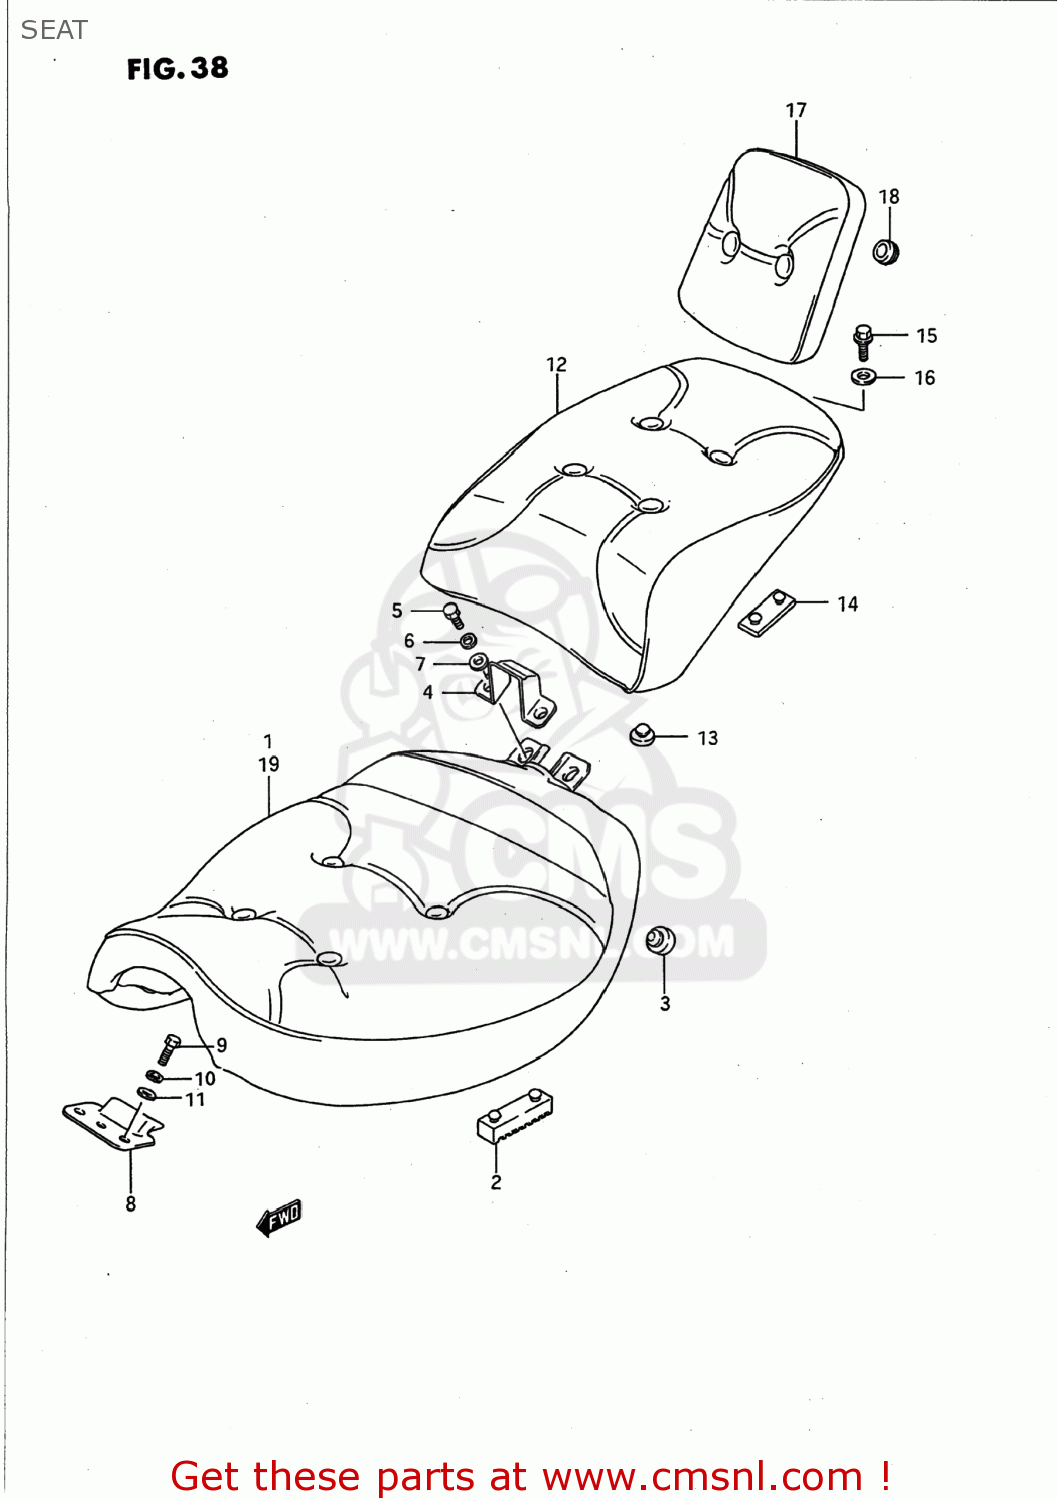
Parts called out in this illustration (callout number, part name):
1	SEAT ASSEMBLY
2	CUSHION,SEAT
3	CUSHION
4	BRACKET,PILLION SEAT FR
5	BOLT
6	LOCK WASHER
7	WASHER
8	BRACKET,SEAT FR
9	BOLT
10	LOCK WASHER
11	WASHER
12	SEAT SET,PILLION
13	CUSHION
14	CUSHION,PILLION SEAT RR
15	BOLT(6X17.5)
16	WASHER (9X19X1)
17	PAD ASSY,SEAT
18	CUSHION
19	SEAT ASSEMBLY
